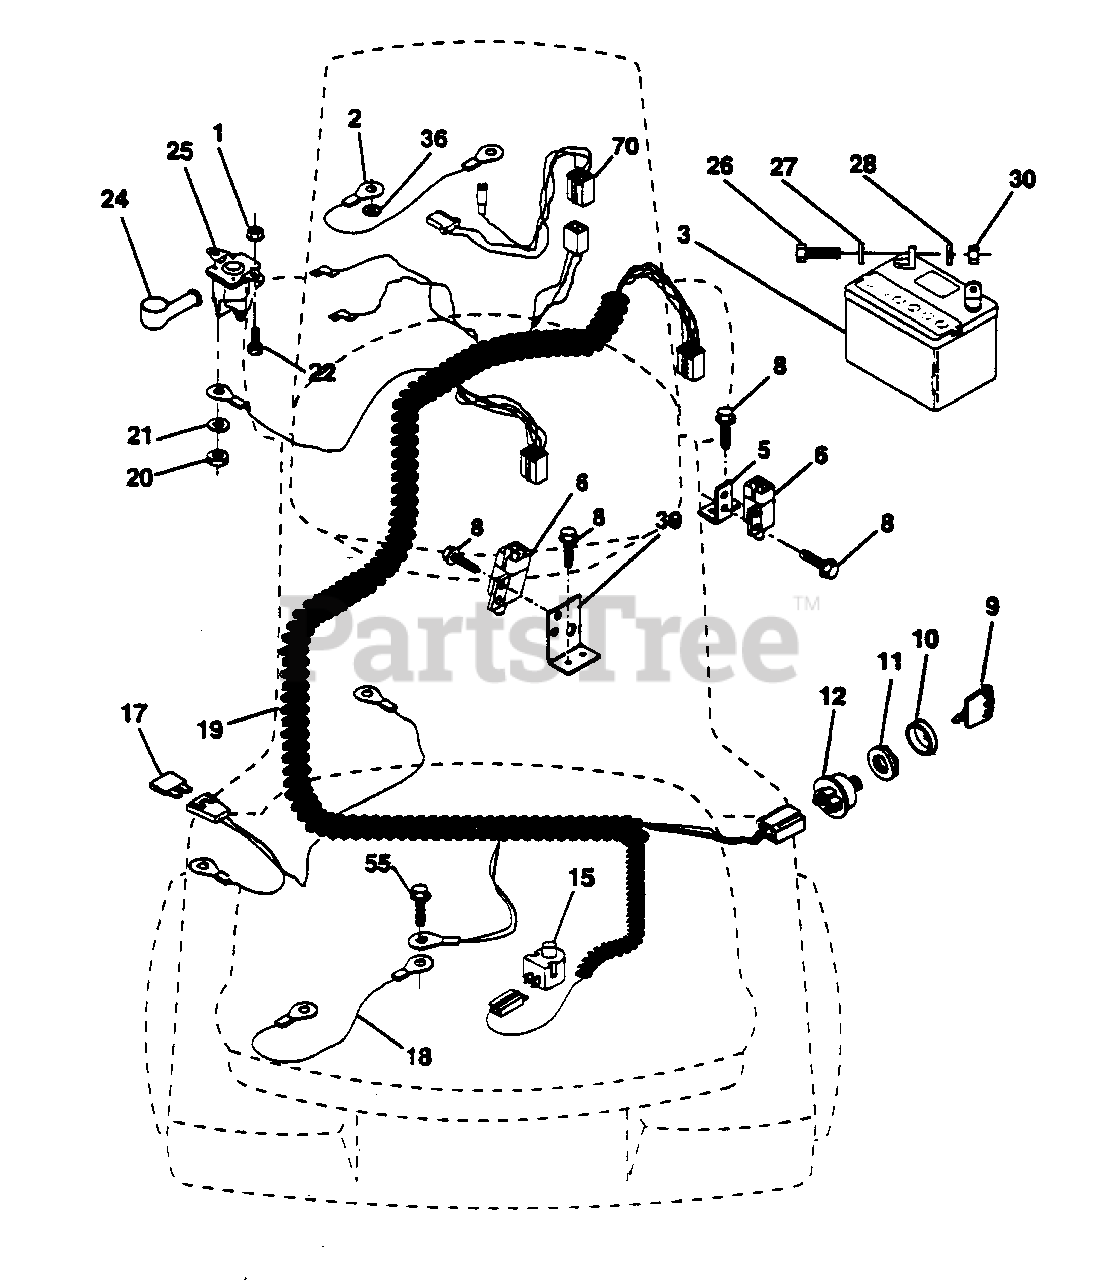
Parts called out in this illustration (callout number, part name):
1	Nut, Hex Keps 1/4-20
2	Assembly, Cable
3	Battery
5	Bracket, Switch
6	Switch, Interlock (4-terminal)
8	Screw, Hex Hd. Tap #10-24 x 1/2
9	Key, Steel Delta
10	Cover, Key Ignition
11	Nut, Ignition
12	Switch, Ignition
15	Switch, Plunger
18	Assembly, Cable
19	Hamess, Ignition
20	Nut, Hex Jam 1/4-20
21	Washer, Lock 1/4
22	Bolt, Fin. Hex 1/4-20 UNC x 1/2 Gr. 5
24	Cover, Terminal
26	Bolt, Hex Hd. 1/4-20 UNC x 3/4
27	Washer 9/32 x 5/8 x 16
28	Washer, Lock 1/4
30	Nut, Fin. Hex 1/4-20 UNC
36	Washer Lock Inter. Tooth 1/4
39	Bracket Switch Clutch
55	Screw, Thdrol. 5/16-18 x 1/2
70	Harness Engine
